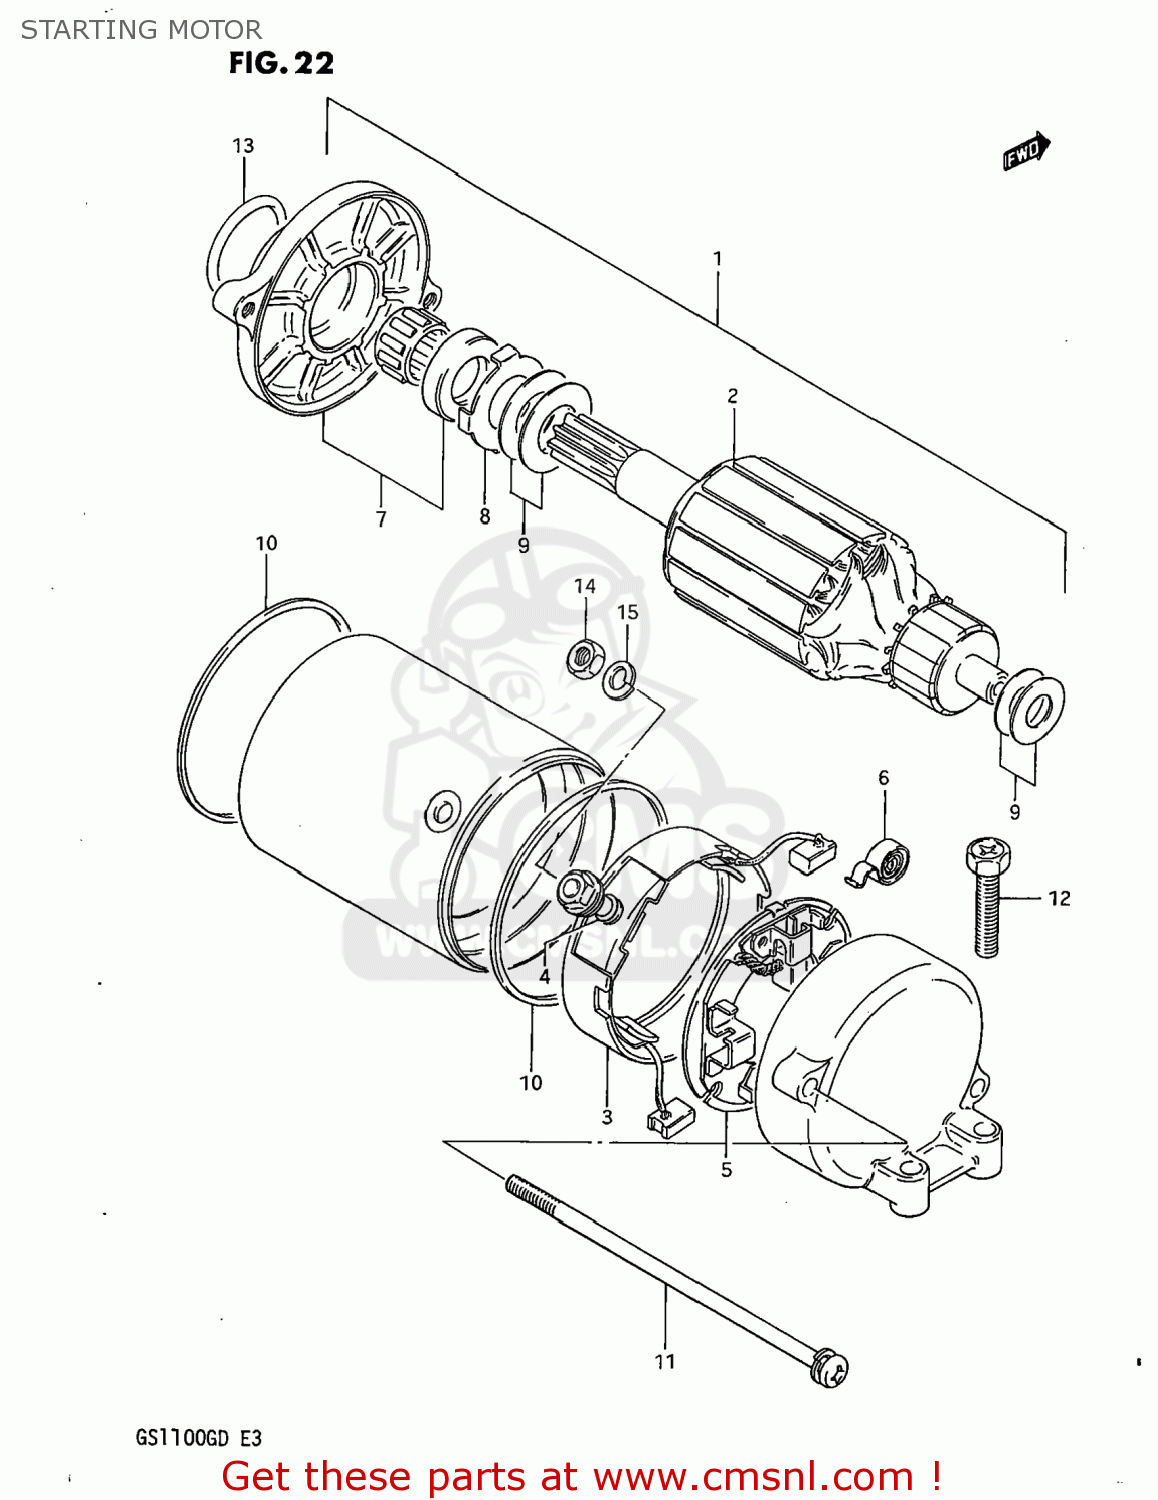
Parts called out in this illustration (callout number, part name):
1	MOTOR ASSEMBLY,STARTING
2	ARMATURE
3	BRUSH TERMINAL SET (+)
4	O RING
5	HOLDER,BRUSH
6	SPRING,BRUSH
7	HOUSING SET,STARTING MOTOR
8	SHIM SET
9	SHIM SET
10	SEAL,RING
11	BOLT,STARTING MOTOR HOUSING
12	SCREW (6X25)
13	O RING(D:2,ID:24.5)
14	NUT 6MM
15	LOCK WASHER
